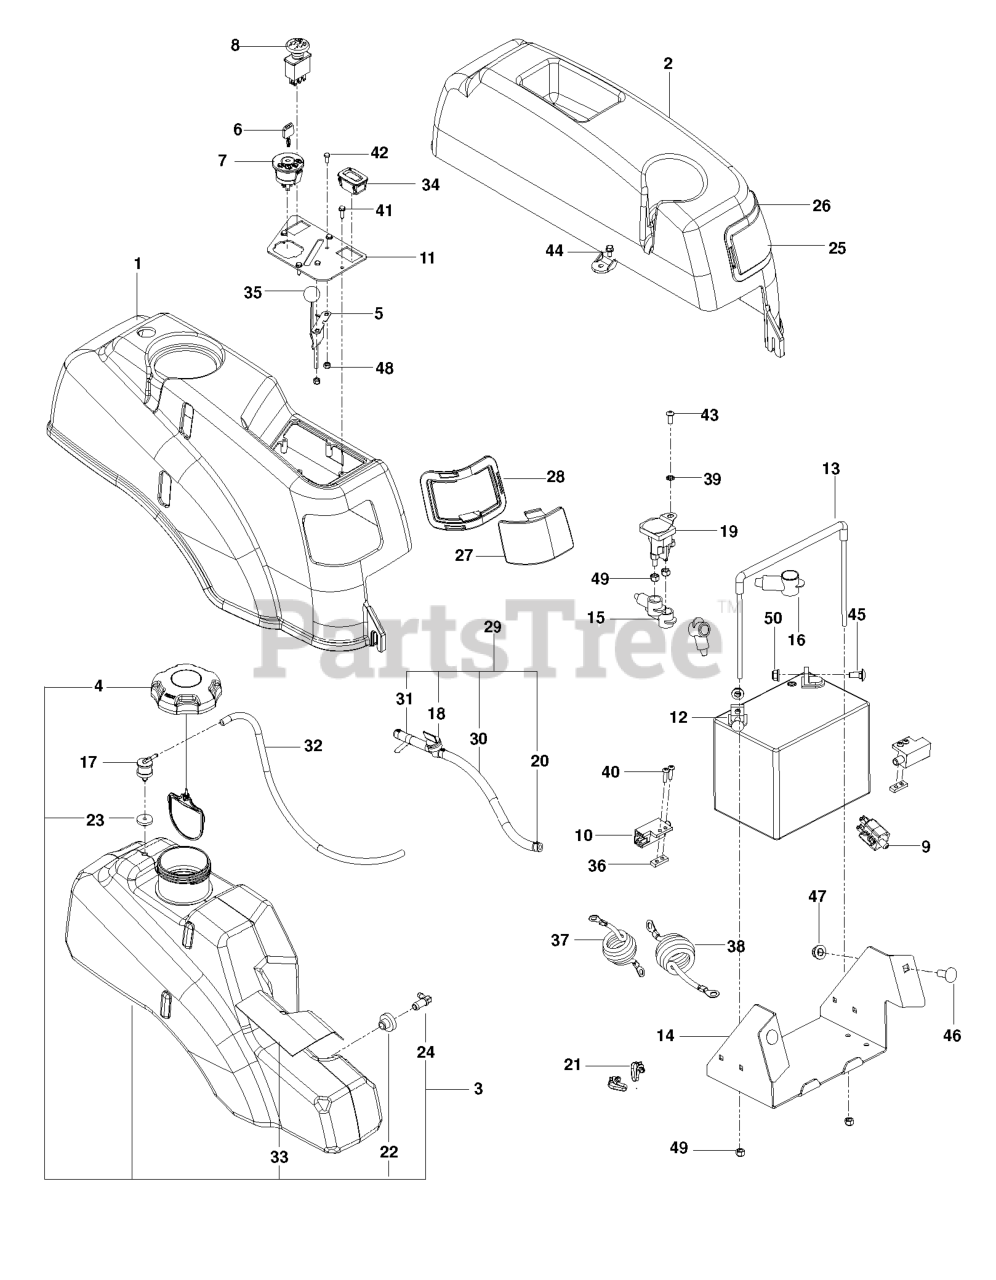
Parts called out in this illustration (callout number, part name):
1	FENDER RT, GRAY
2	FENDER, LT
3	TANK.FUEL.ASSEMBLY.LARGE
4	CAP, FUEL
5	CABLE.THROTTLE.37"
6	KEY MLD GEN DELTA
7	RP IGNITION SWITCH
8	RP SWITCH.PTO.8.TERMINAL.RED
9	SWITCH, BRAKE 3P
10	SWITCH INTERLOCKT
11	PLATE.CONTROL.R/START.RZ.X431
12	BATTERY, 12 V 330 AMP
13	BATTERY TIE DOWN ASSEMBLY
14	BOX, BATTERY, BLACK
15	TERMINAL COVER
17	VALVE.FUEL.CHECK
18	FUEL VALVE
19	SOLENOID.W/BRASS.PLUNGER
20	HOSE CLAMP
21	TIE WRAP, 8-3/8", W/CLIP
22	RUBBER GROMMET
23	GROMMET, CHECK VALVE
24	STEM, FUEL TANK
25	LENS, COLORED LEFT
26	LEFT HEADLIGHT RIM GREY
27	LENS, COLORED RIGHT
28	RT HEADLIGHT RIM GREY
29	FUEL LINE ASSY
30	GAS LINE 10"
31	FUEL LINE 3"
32	HOSE, FUEL, 3/16" X 20"
33	SHIELD, HEAT
34	RP.GUAGE.SRVCMNDR.HRMTR.
35	KNOB.ROUND.BALL.BLACK
36	TAPPED PLATE
37	BATTERY CABLE, NEGATIVE
38	CABLE POSITIVE, LONG
39	WASHER 1/4 INT TOOTH
40	SCR #10-24 X .75 SKT HD BLK
41	SCR #10-12X3/4 HEX WAS HD ZD
42	HCS #10-24 X 1/2
43	SCR 1/4-20 X 5/8 BTN SKT HD ZD
44	SCREW
45	RP BOLT 5/16-18 X3/4 ZN/YEL GR
46	BOLT D
47	NUT 3/8-16 HEX FLG NYLOC ZD
48	NUT 10-24 NYLOC
49	LOCKNUT.NYLOC.1/4-20
50	5/16-18 NYLOC FLANGE NUT
